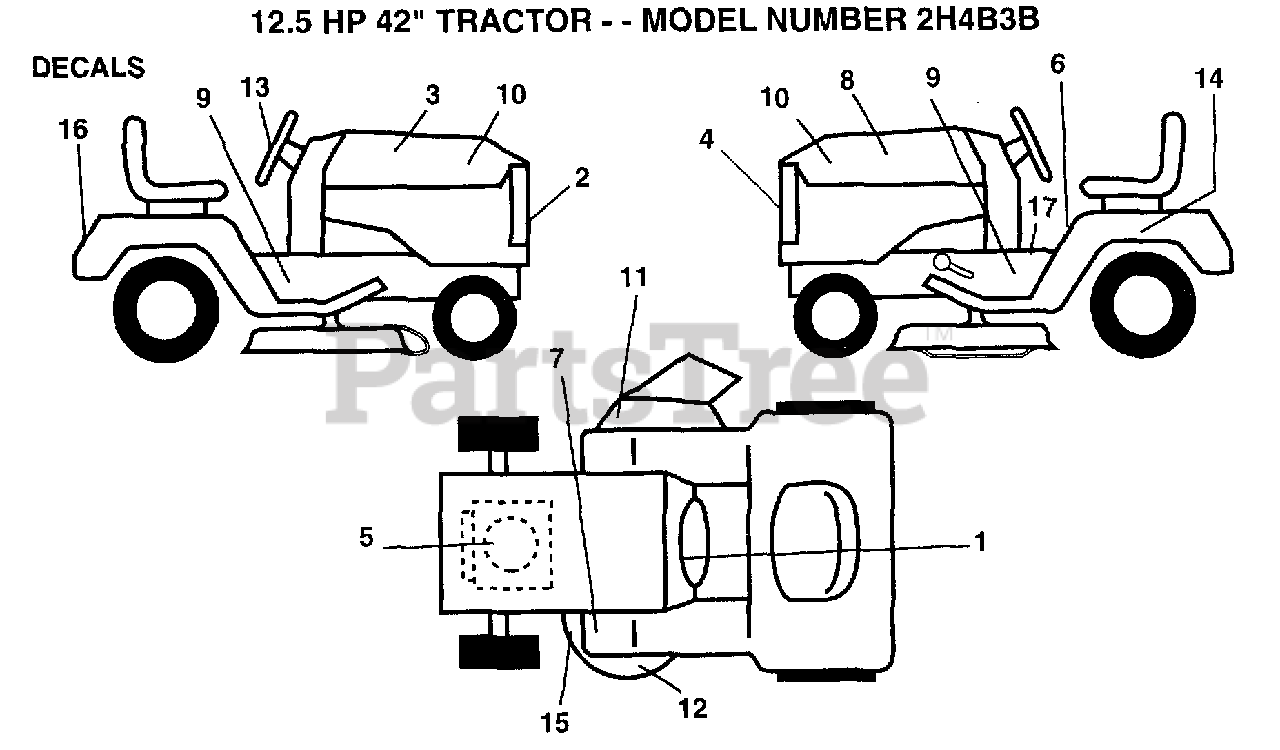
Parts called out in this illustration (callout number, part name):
1	DECAL.DASH.INSTR.
2	GRILL DECAL
3	DECAL HOOD RH RLY
5	DECAL.ENG.272632
6	DECAL CAUTION
7	DECAL T
8	DECAL HOOD LH RLY
9	CHASSIS DECAL
11	"DECAL, WARNING"
13	"DECAL,STR WHL"
14	DECAL
15	DECAL.V.BELT
16	FENDER DECAL
17	DECAL BRAK PARK
